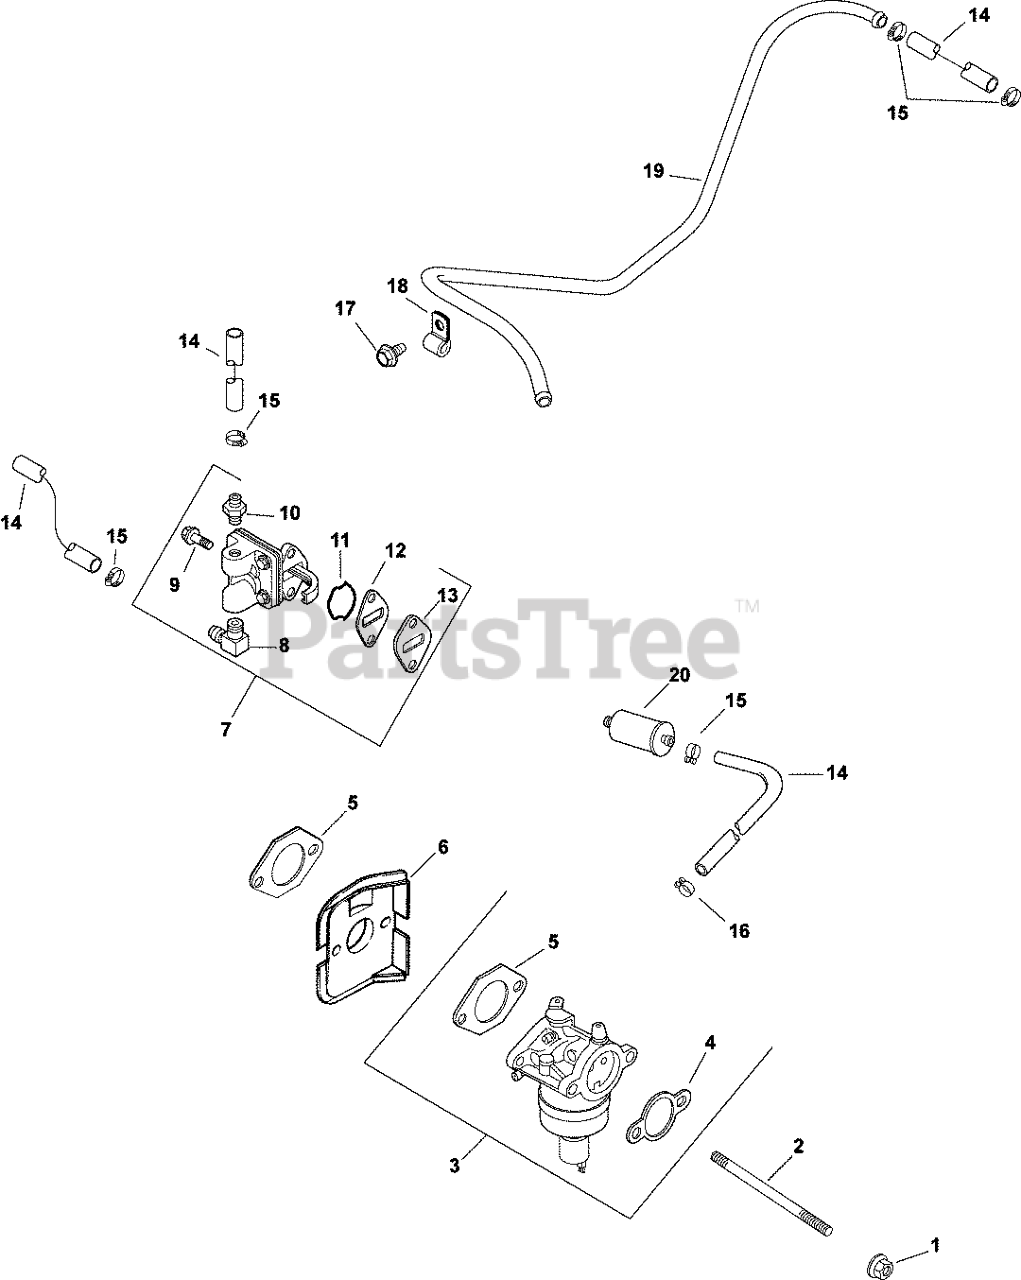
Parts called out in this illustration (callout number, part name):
1	NUT, FLG M6X1.0
2	STUD,M6X1.0X116
3	KIT, CARBURETOR w/GASKETS
4	GASKET, AIR CLEANER BASE
5	GASKET, CARBURETOR
6	DEFLECTOR, HEAT
7	KIT, FUEL PUMP
8	CONNECTOR, 90 DEG. HOSE
9	SCREW, LBD SKT M6x1.0x20-(#25086403S)
10	KIT, STRAIGHT FITTING
11	O-RING, FUEL PUMP
12	GASKET, FUEL PUMP
13	SPACER, FUEL PUMP
14	HOSE,LW PERM.FUEL 24.00"-USE 25 111 81-S
15	CLAMP, HOSE (KM)-USE 25 237 31-S
16	CLAMP, BAND SPRING HOSE-(#2523737S)
17	SCREW, FLG THD FRM M5X.8X10
18	CLIP, TUBE & WIRING (KM)
19	LINE, FUEL
20	FILTER,FUEL 51 MICRON (FUEL PUMP)
